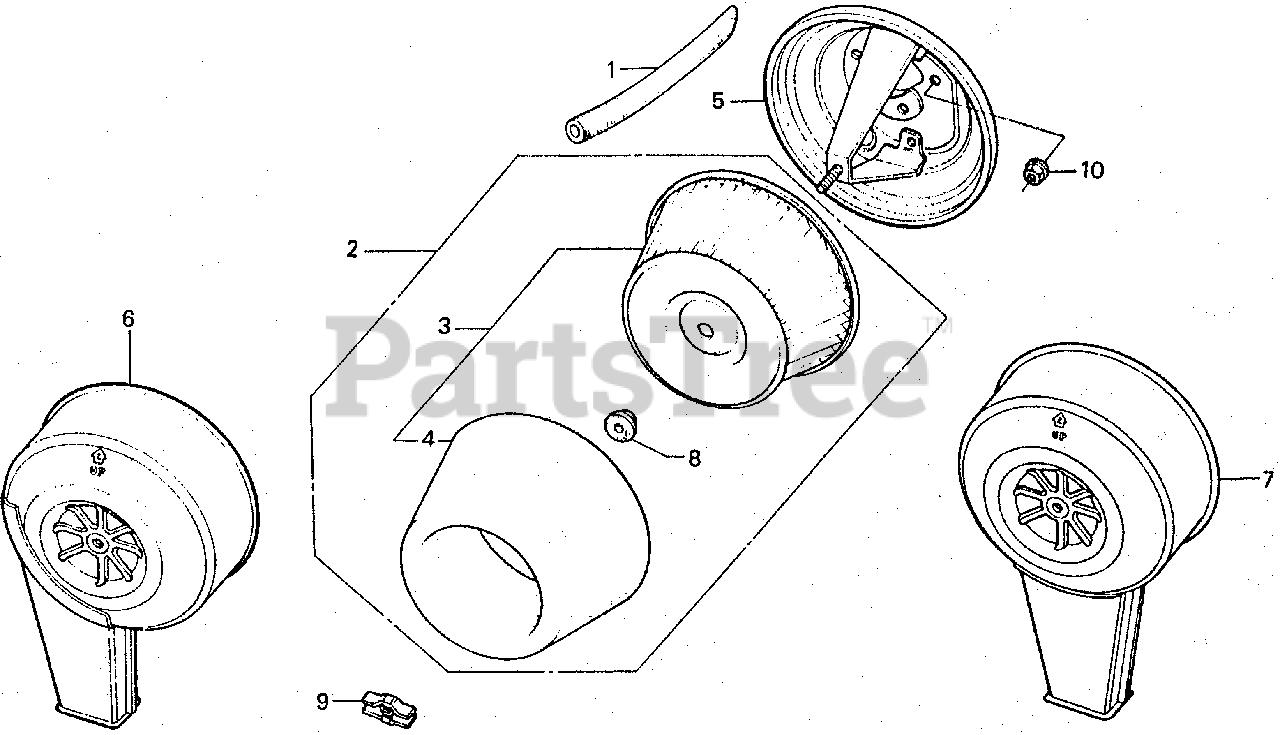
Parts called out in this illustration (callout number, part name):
1	TUBE, BREATHER
2	ELEMENT, AIR CLEANER
3	ELEMENT, AIR CLEANER
4	FILTER (OUTER)
5	HOUSING, AIR CLEANER (NOT AVAILABLE)
7	COVER, AIR CLEANER
8	GROMMET, AIR CLEANER
9	NUT, AIR CLEANER COVER (DACRO COATING)
10	NUT, FLANGE (6MM)
